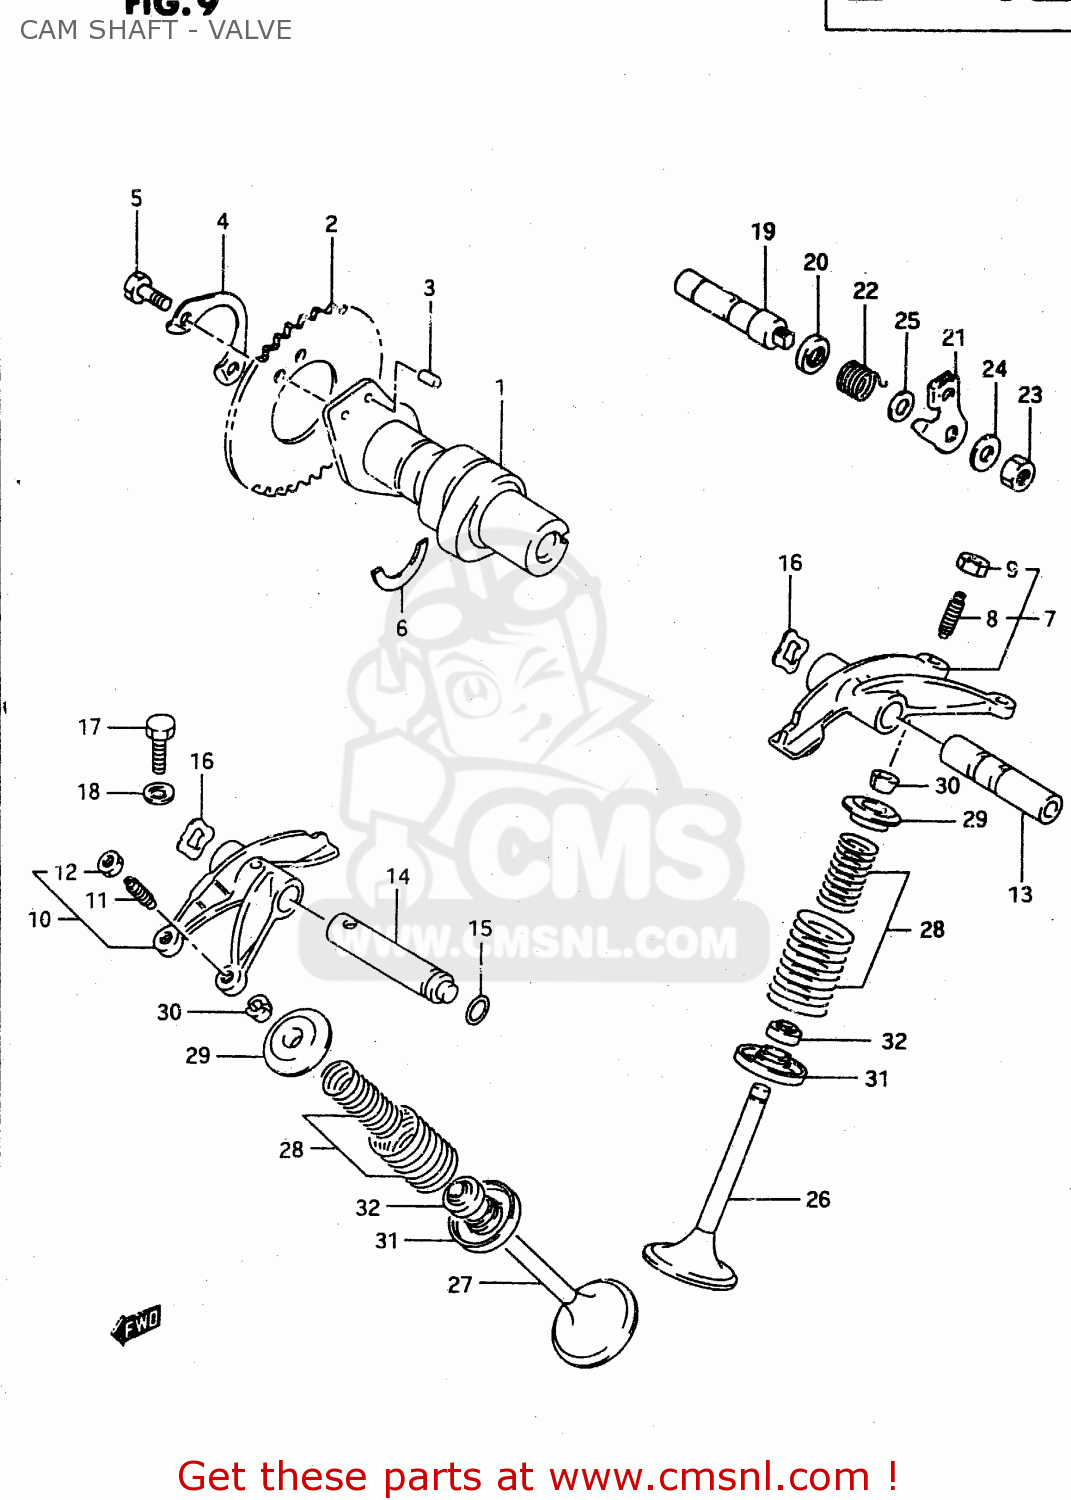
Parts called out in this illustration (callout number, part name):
1	CAMSHAFT
2	SPROCKET,CAMSHAFT(NT:42)
3	PIN
4	WASHER,CAM CHAIN SPROCKET
5	BOLT(6X12.5)
6	C RING
7	ARM,VALVE ROCKER INTAKE
8	SCREW,TAPPET ADJUSTING
9	NUT,ADJUSTING SCREW
10	ARM,VALVE ROCKER EXHAUST
11	SCREW,TAPPET ADJUSTING
12	NUT,ADJUSTING SCREW
13	SHAFT,VALVE ROCKER ARM INTAKE
14	SHAFT,EXHAUST VALVE ROCKER ARM
15	O RING(D:1.9,ID:8.6)
16	WASHER
17	BOLT
18	GASKET(5.8X13X1.2) (NAS)
19	SHAFT,DECOMP
20	SEAL,OIL(10X17X6)
21	LEVER,DECOMPRESSION SHAFT
22	SPRING
23	NUT
24	WASHER
25	WASHER(8.5X13X1.6)
26	VALVE,INTAKE
27	VALVE,EXHAUST
28	SPRING SET,VALVE
29	RETAINER,VALVE SPRING
30	COTTER VALVE
31	SEAT,VALVE SPRING
32	SEAL,OIL(7X14.4X9)
